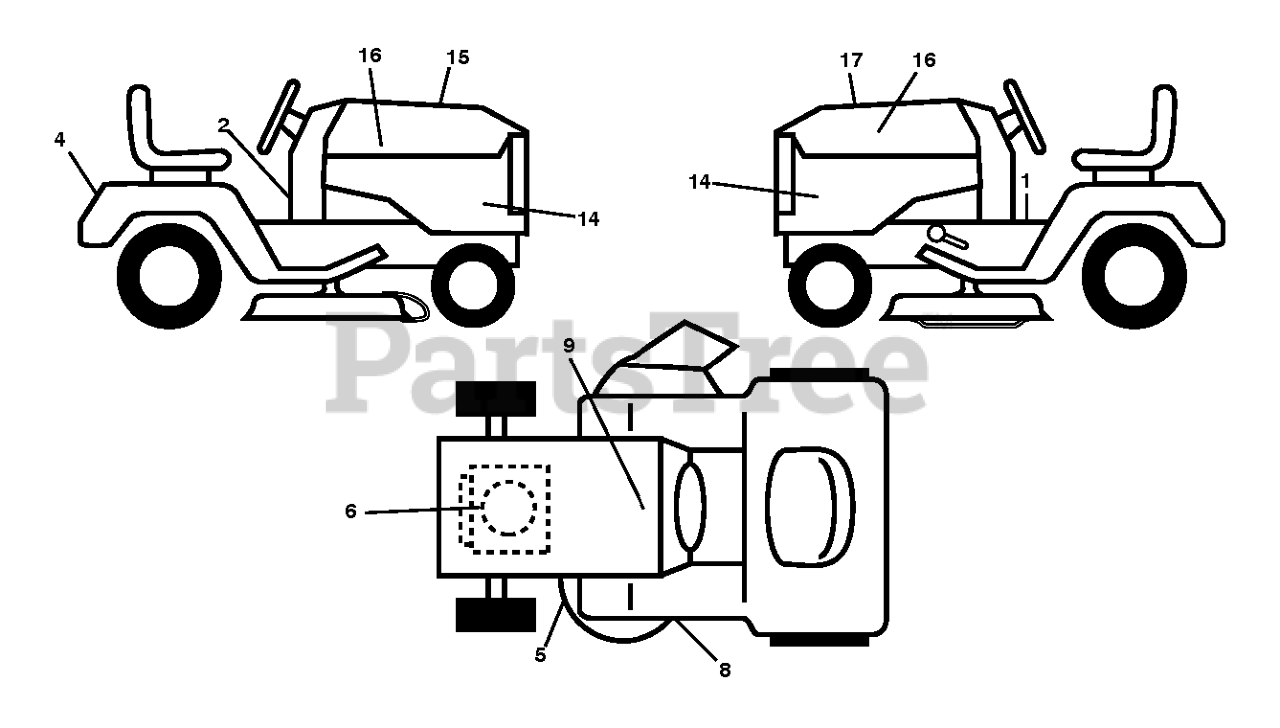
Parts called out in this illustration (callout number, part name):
1	DECAL.WARN.START.INSTRUCTIONS
2	DECAL, WARNING SPARK ARRESTOR
4	DECAL.FENDER
5	DECAL.MOWER
6	DECAL.ENG.BS.23HP.XRD.TWIN
8	DECAL.MOWER.SCH.48/54
9	DECAL BTRY SYMBOLS
14	DECAL.SDPNL.HUSGT2.YTH2348.HUS
15	DECAL.WARNING.CUST.RESP.E85.
16	DECAL.BADGE.170MM.TEXTLOGO.
